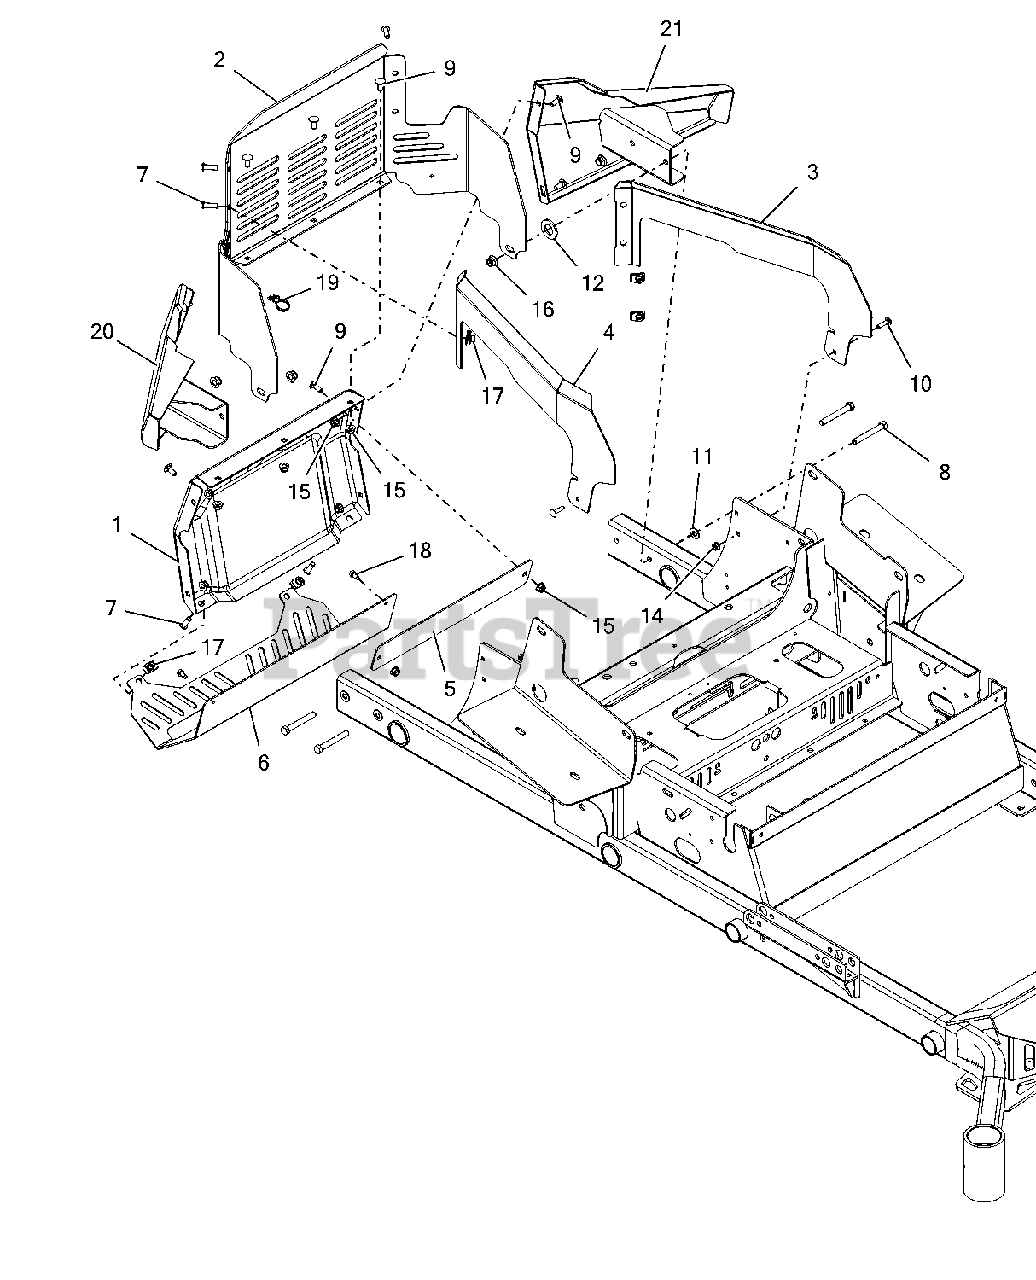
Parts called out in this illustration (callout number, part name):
1	PT200/400 REAR BUMPER - BLACK
2	PT400 ENGINE GUARD - BLACK
3	HOOD STYLE TRIM (LEFT) - RED
4	HOOD STYLE TRIM (RIGHT) - RED
5	BACKER PLATE - RED
6	PT200/400 MUFFLER GUARD - BLK
7	SCR-SKH .31-18X1.0 BTNHD YWZC
8	@BLT-HEX .38-16X2.75 GR5 YWZC
9	@BLT-RDHDSQNK .31-18X.75 G5YZ
10	@BLT-RDHDSQNK .25-20X1.00 G5YZ
11	@WSHR-FL-STL.406X.812X.065 YWZ
12	@WSHR-FL-STL.812X1.50X.135YWZC
14	@NUT-LK-NYL-FLG .25-20 YWZC
15	@NUT-LK-NYL-FLG .31-18 YWZC
16	@NUT-LK-NYL-FLG .38-16 YWZC
17	NUT-CLIP RETAINER 5/16-18X.56
18	SCR-TAP .25-20X.50 HWH TR YWZ
19	CABLE TIE W/ TREE (.25 HOLE)
20	WMT,RH REAR BMPR WING W/DECAL
21	WMT,LH REAR BMPR WING W/DECAL
